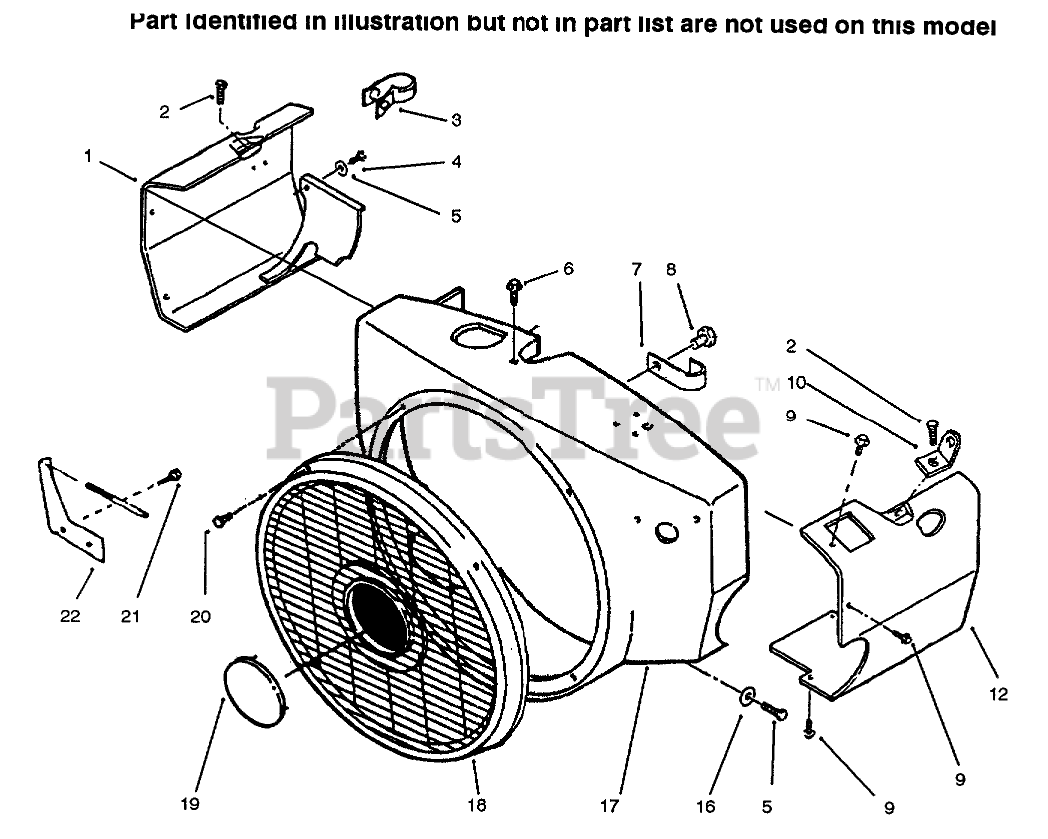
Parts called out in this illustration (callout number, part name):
1	LH AIR CYLINDER HSG
2	SCREW-HWH
3	WIRE CLAMP
4	SCREW-HH
5	WASHER-FLAT
6	HEX HD CAPSCREW
7	CLIP-WIRE
8	SCREW-HWH
9	SCREW-HWH
10	BRACKET-LIFTING
12	RH AIR CYLINDER HSG
16	WASHER-FLAT
17	BLOWER-HOUSING
18	GUARD-STATIONARY
19	NAME-PLATE TORO LOGO
20	SCREW-PAN HEAD
21	SCREW-HWH
22	BRACKET
